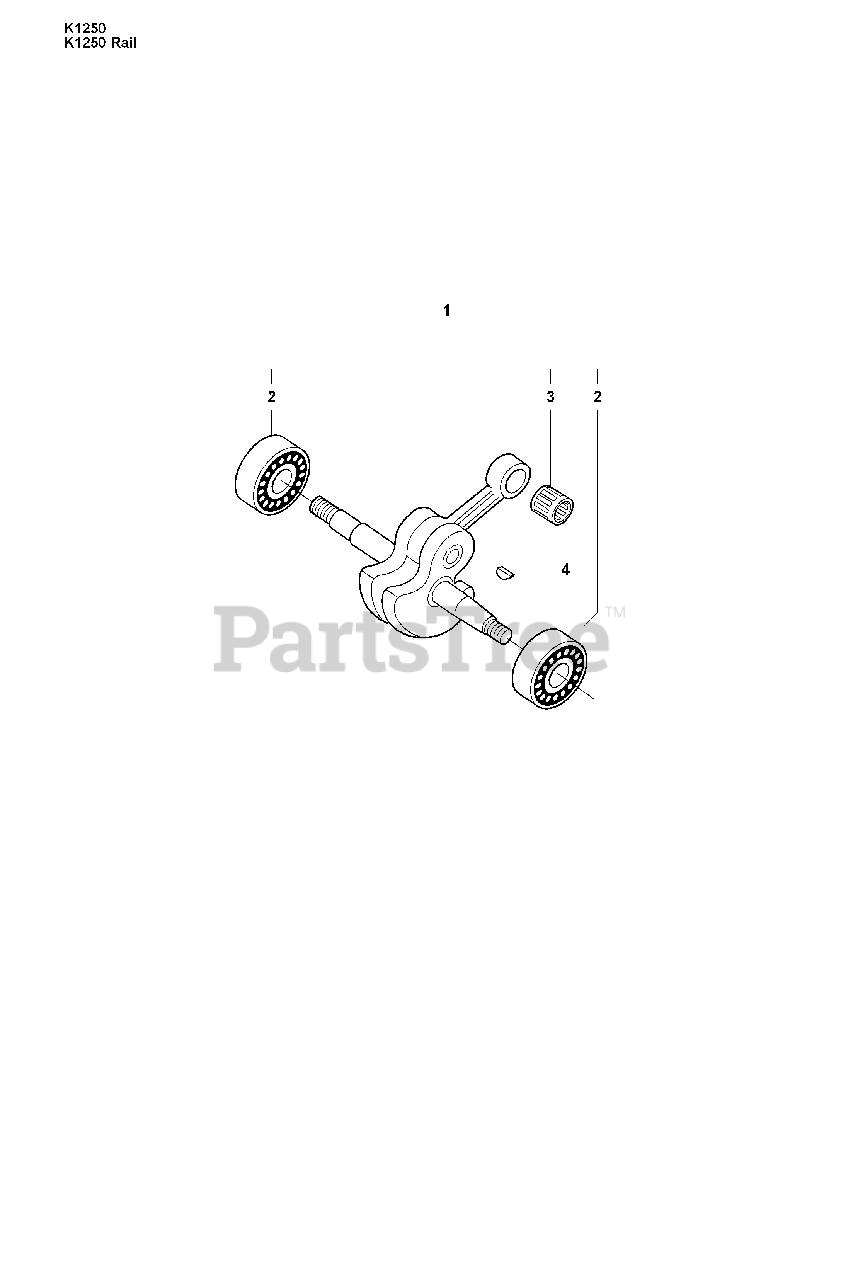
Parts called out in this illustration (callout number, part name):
1	CRANKSHAFT ASSY
2	BALL BEARING
3	SUPPORT BUSHING
4	WOODRUFF KEY
